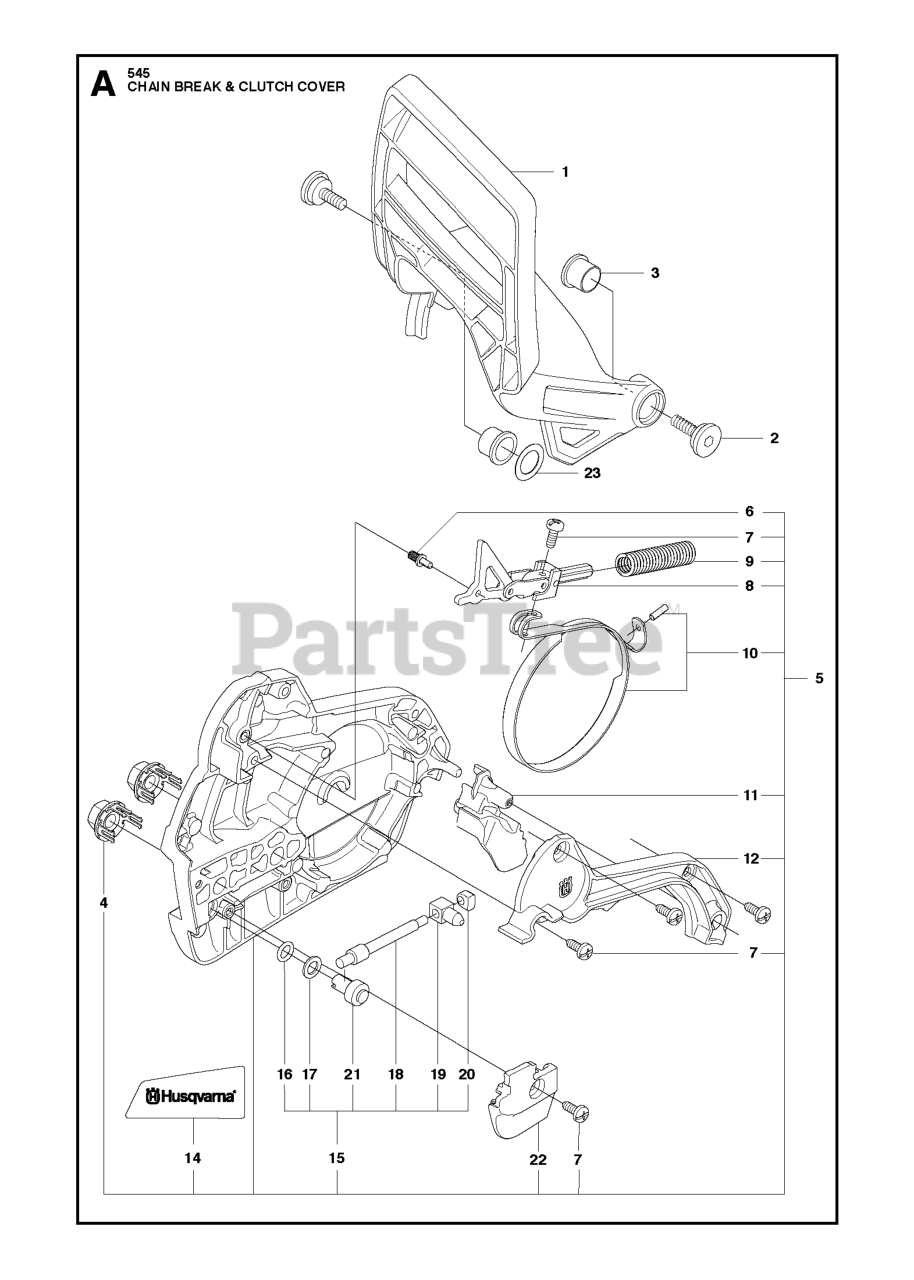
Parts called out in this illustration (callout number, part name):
1	HAND GUARD
4	NUT RETAINER ASSY
5	CLUTCH COVER ASSY
6	PIN
7	SCREW
8	KNEE JOINT ASSY
9	SPRING
10	BRAKE BAND ASSY
11	GUARD
12	COVER
14	LABEL
15	CHAIN TENSIONER KIT
16	O-RING
17	WASHER
18	SCREW
19	PAWL
20	SLEEVE
21	WORM WHEEL
22	CHAIN GUIDE
23	WASHER STEEL
